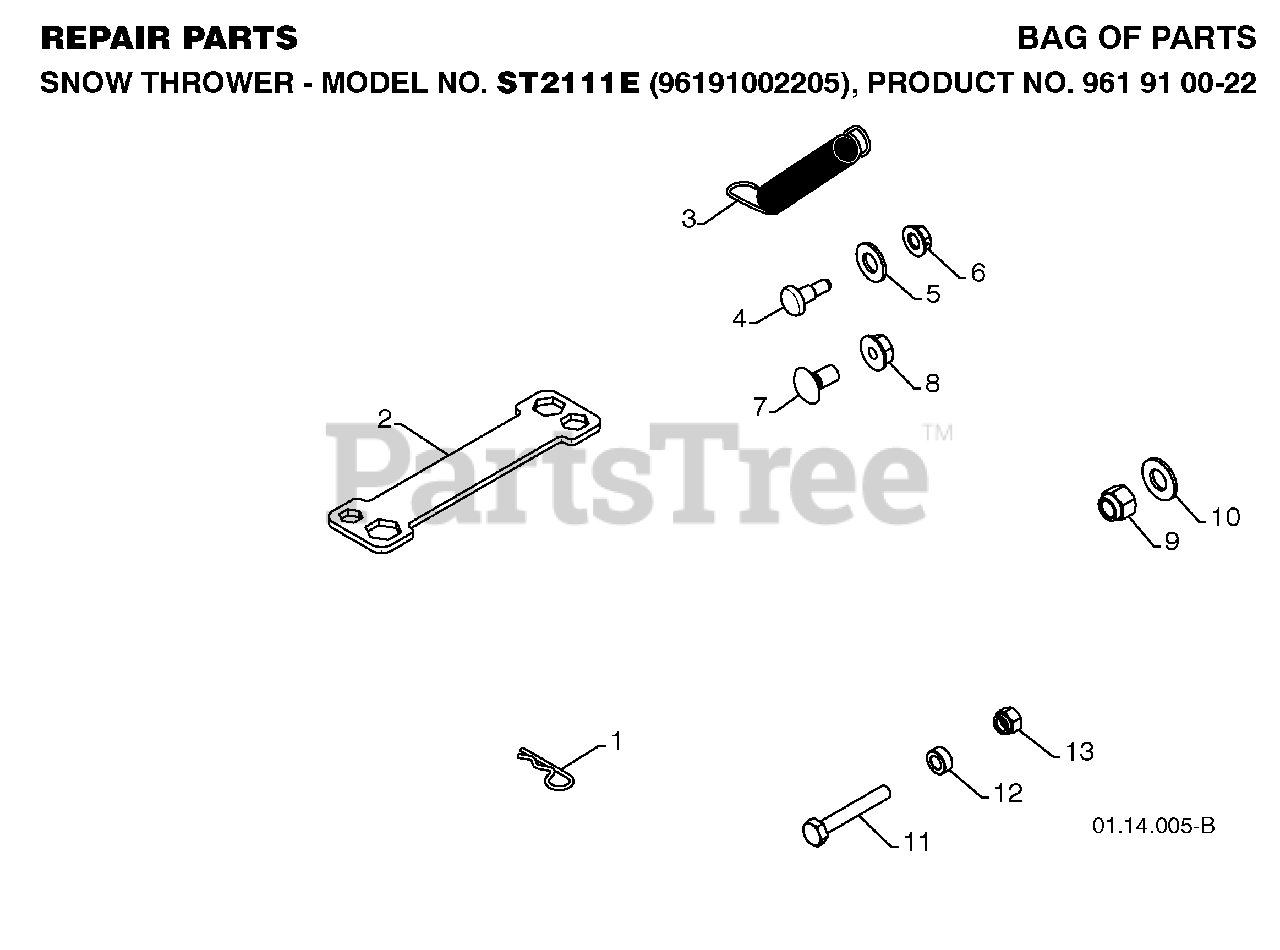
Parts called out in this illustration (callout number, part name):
1	SPRING RETAINER
2	RP WRENCH, SNOWTHROWER
4	BOLT, SHOULDER
5	WASHER, NYLON FRICTION
6	NUT.HEX.FLANGE.1/4
7	BOLT
8	NUT, LOCK 5/16-18
9	NUT
11	BOLT, SHEAR
13	LOCKNUT
